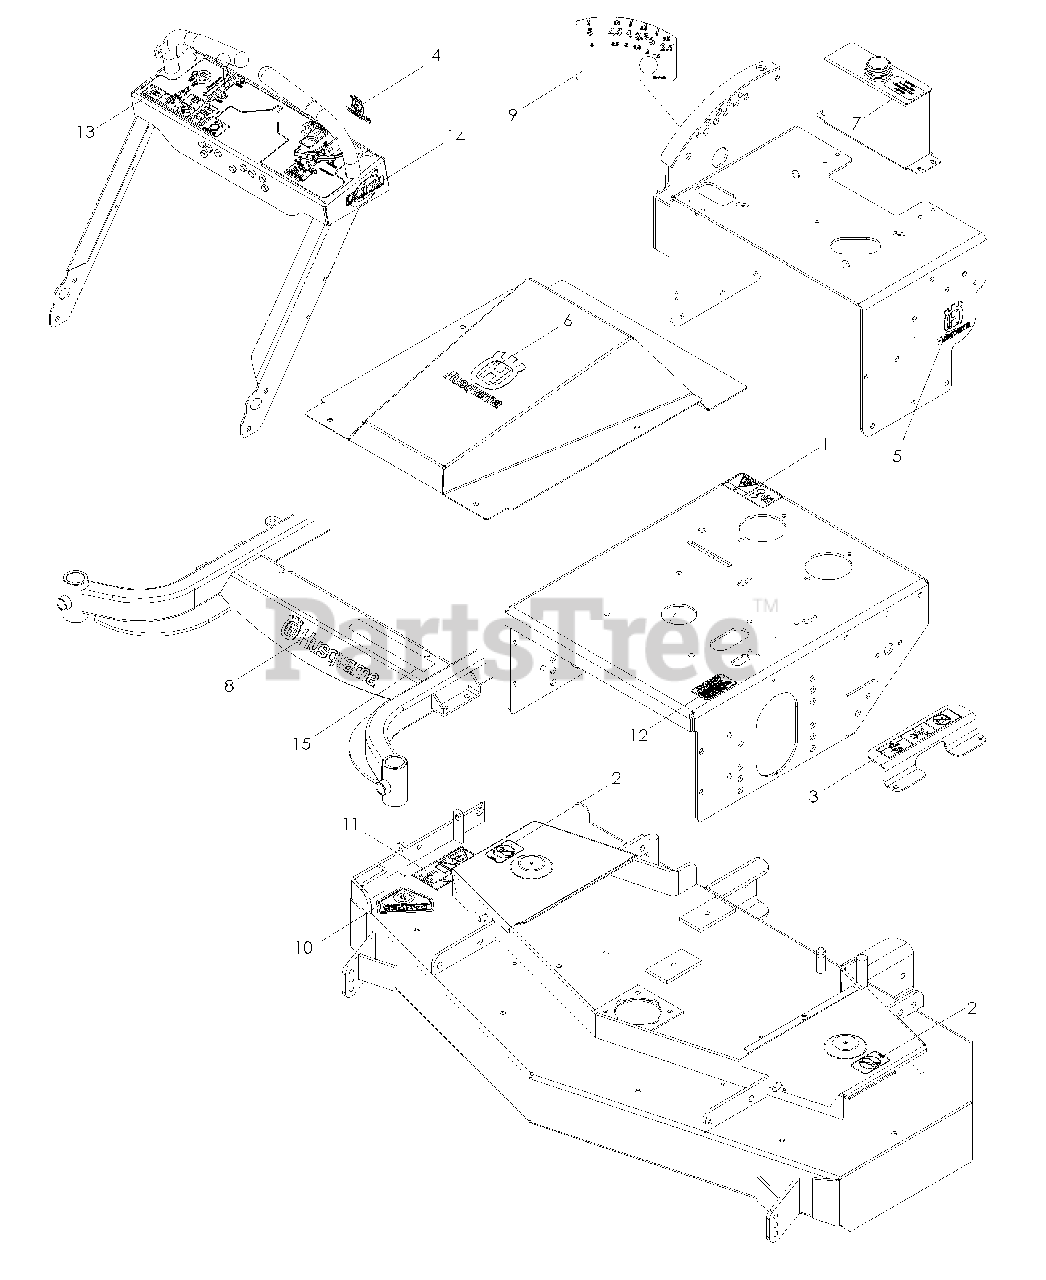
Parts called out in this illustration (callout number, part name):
1	DECAL, BELT DRIVES
2	DECAL, NO STEP
3	DECAL, BATTERY WARNING
4	DECAL, CROWN 2 1/4
5	DECAL, CROWN 3 1/8"
6	DECAL, CROWN 5 1/4"
7	DECAL, OIL TANK
8	DECAL, HUSQ 9 1/4"
9	DECAL, CUT HEIGHT
10	DECAL, CPSC
11	DECAL, SEVERING
12	DECAL, PROP 65
13	DECAL, CONSOLE
14	DECAL, ETS
15	DECAL, WHF4817
15	DECAL, WHF5219
15	DECAL, WH5221
